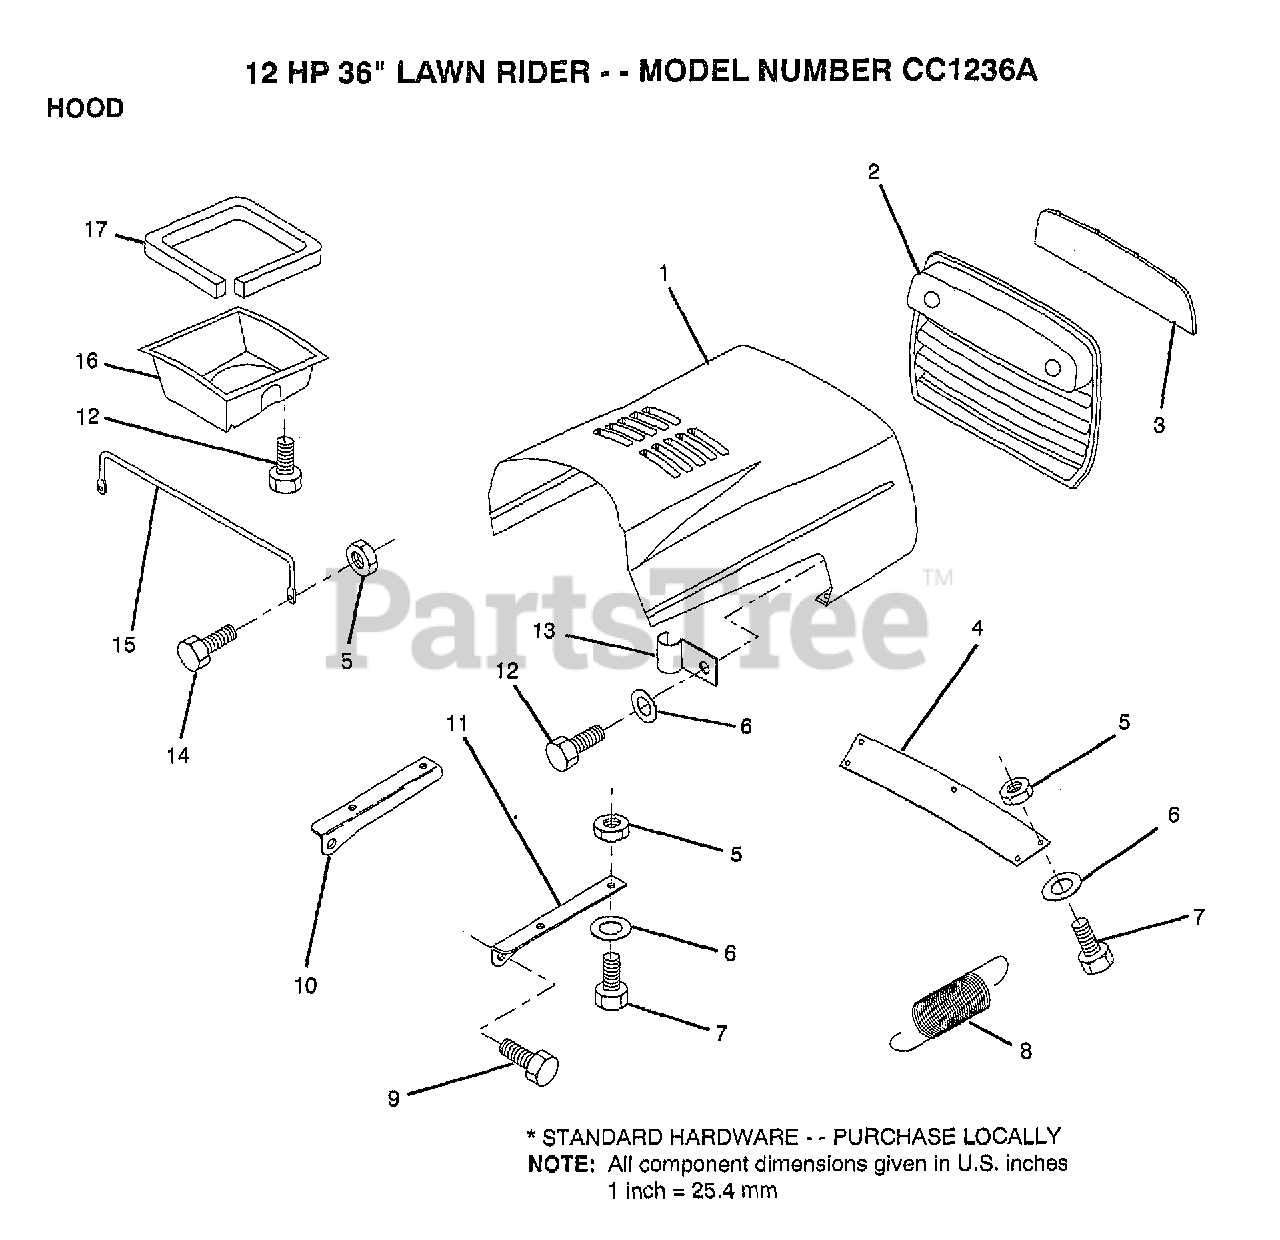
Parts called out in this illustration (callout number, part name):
2	GRILL
3	LENS
5	NUT
6	WASHER
7	BOLT
8	EXT SPRING
10	BRKT HOOD LH
11	BRKT HOOD RH
13	CLIP T
15	"BRACE,HOOD"
16	"DUCT,AIR"
17	FOAM STRIP LT
